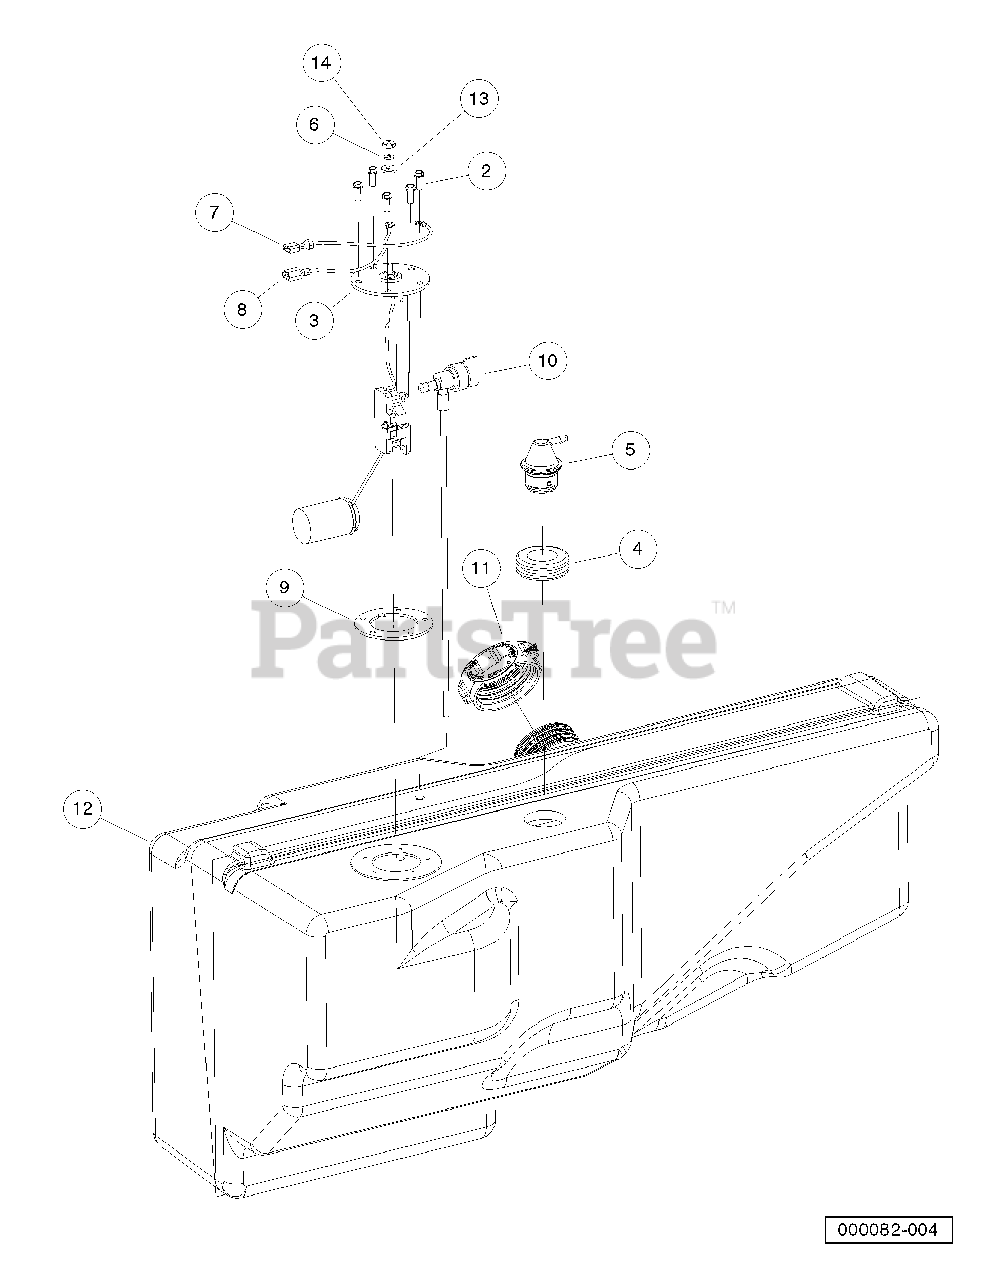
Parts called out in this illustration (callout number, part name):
1	Asm, Tank, Fuel, Gas, 4x4
2	Screw, #1016 HexHead HiLo
3	Sending Unit, Fuel Level
4	Insulation Grommet
5	Vent, Fuel Tank
6	Washer, #10 Split Lock
9	Gasket, Rubber
10	Valve, Pickup Tube, Fuel
11	Cap, Fuel Tank, Gasoline
13	Washer, #10 Type A Flat
14	Nut, #1032 Brass Hex
